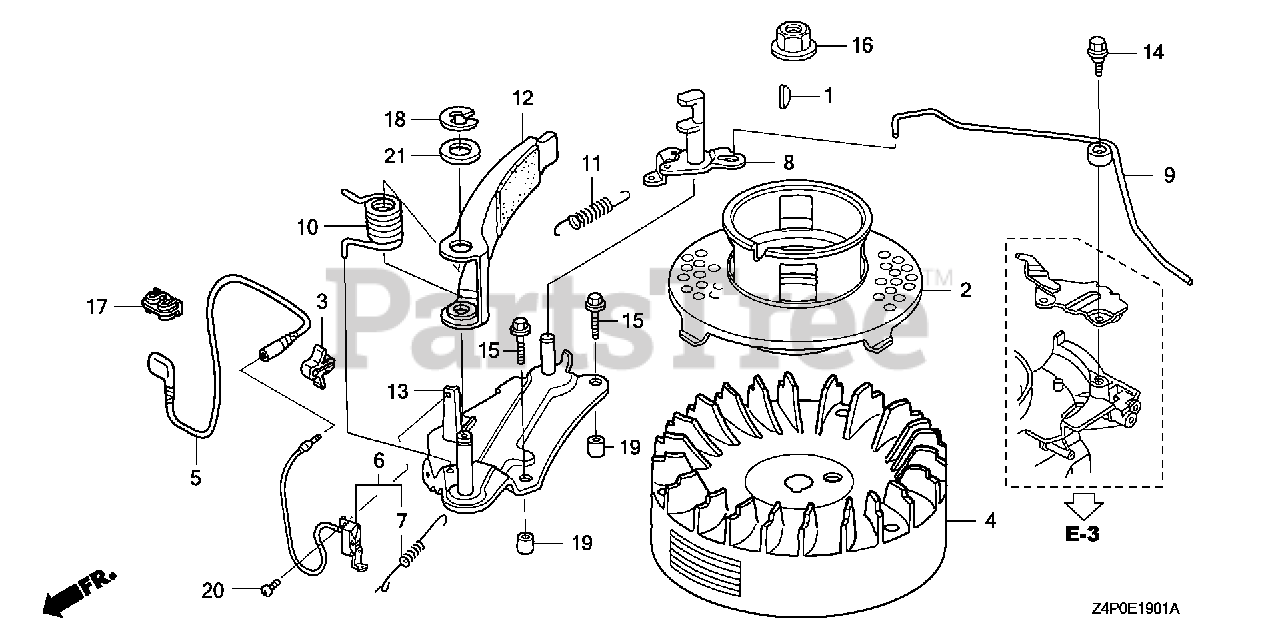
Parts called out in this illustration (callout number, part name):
1	KEY, SPECIAL WOODRUFF (25X18)
2	PULLEY, STARTER
3	CLIP, IGNITION WIRE (8MM)
4	FLYWHEEL (BRAKE)
5	WIRE, STOP SWITCH (BRAKE)
6	SWITCH ASSY., ENGINE STOP (BRAKE)
7	SPRING, SWITCH CONTROL
8	CAM, BRAKE
9	ROD, THROTTLE RETURN
10	SPRING, BRAKE
11	SPRING, BRAKE RETURN
13	BASE, BRAKE
14	BOLT, FLANGE (6MM)
15	BOLT, FLANGE (6X23) (CT200)
16	NUT, SPECIAL (14MM)
17	CLAMP, PIPE
18	E-RING (10MM)
19	PIN, DOWEL (8X9)
20	SCREW, PAN (4X8)
21	WASHER, PLAIN (12MM)
